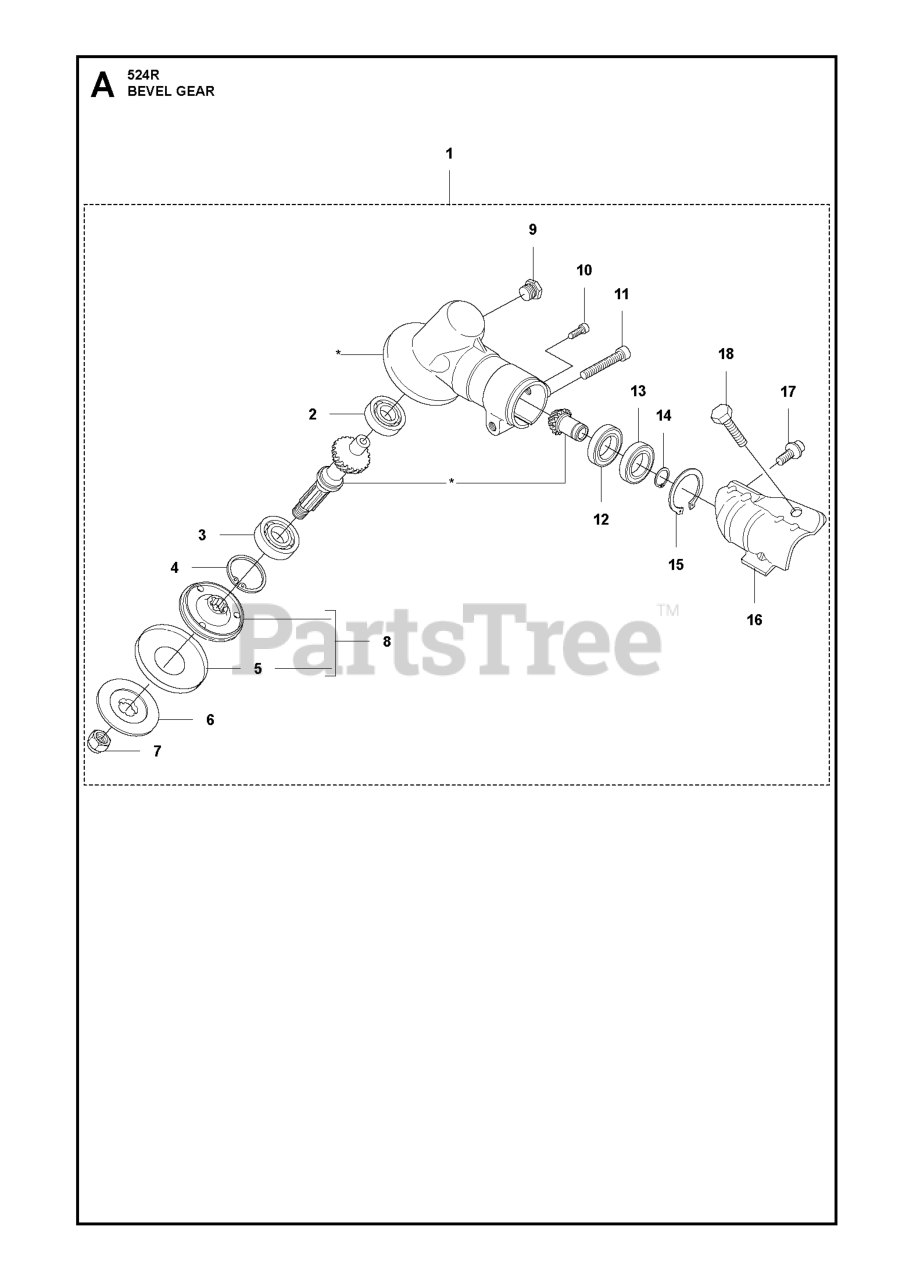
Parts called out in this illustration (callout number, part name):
1	GEAR HEAD
2	BALL BEARING 8X22X7/608Z
3	BEARING
4	RETAINING RING SGH 28
5	WASHER
6	SUPPORT FLANGE
7	GEARHEAD NUT - BRUSHCUTTER
8	DRIVE DISC
12	BALL BEARING 24X9X1/609ZR
14	RETAINING RING
15	RETAINING RING
16	RP BRACKET TRIMMER GUARD
18	SCREW M6S 6X20
